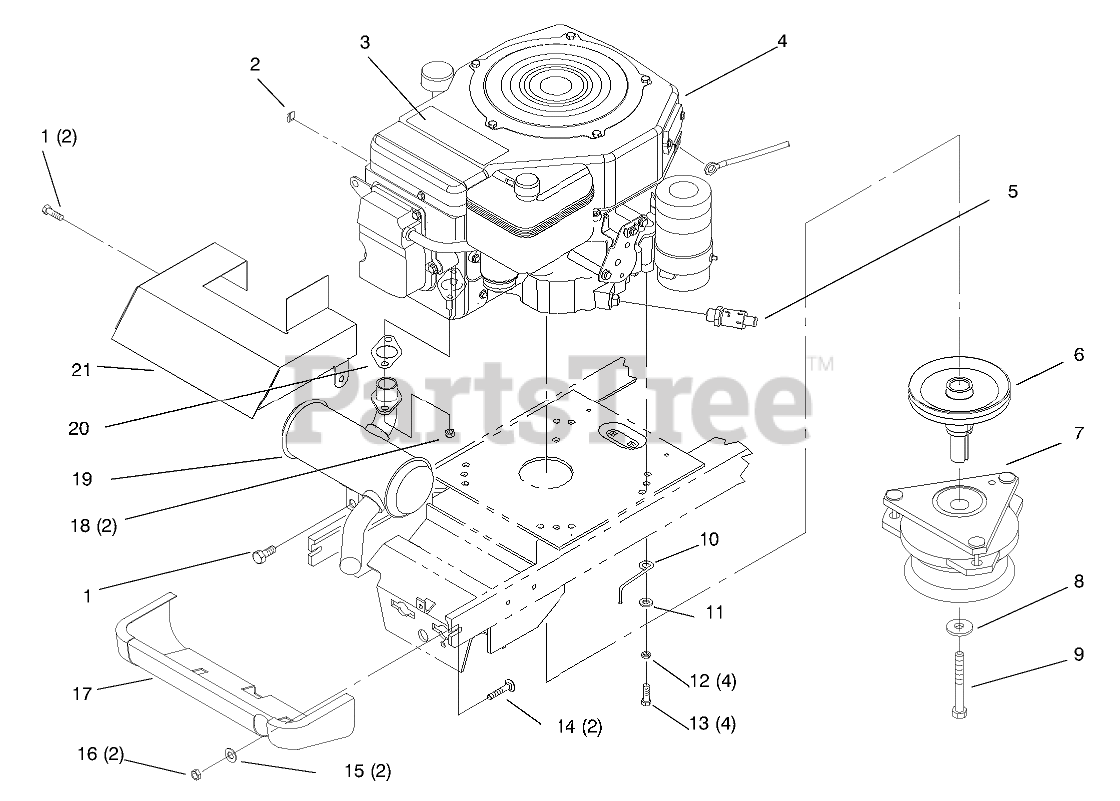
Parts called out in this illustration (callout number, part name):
1	SCREW-HWHTF
2	CLIP-RETAINER, WIRE
3	DECAL - LOGO
4	ENGINE - KOHLER 15
5	VALVE-DRAIN, OIL
6	PULLEY- ENGINE GEAR
7	CLUTCH - PTO
8	WASHER
9	SCREW-HH
10	GUIDE-BELT
11	WASHER-PLAIN
12	WASHER-LOCK
13	SCREW-HH
14	BOLT-CARR
15	WASHER-FLAT
16	NUT-LOCK, NI
17	Shield-Muffler
18	NUT-HF
19	Muffler
20	Gasket-Exhaust
21	SHIELD-MUFFLER
